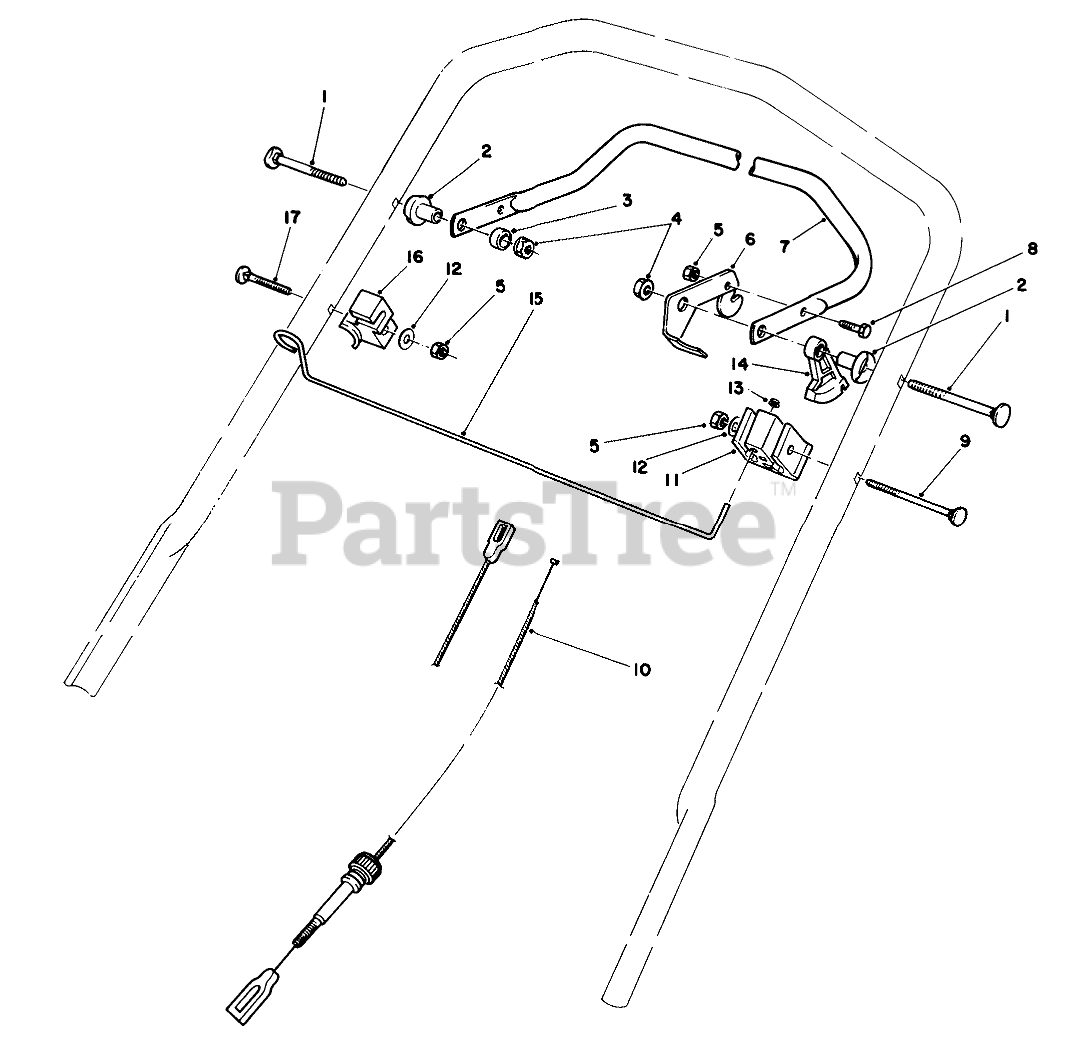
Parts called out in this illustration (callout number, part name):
1	5/16-18 X 2 HNDLE SCREW
2	SPACER-SUPPORT
3	SPACER-NYLON
4	NUT-LOCK, NI
5	NUT-LOCK, NI
6	Lever-Control
7	Bar-Control
8	SCREW-HH
9	HANDLE SCREW
10	CABLE-TRACTION
11	SUPPORT-CABLE
12	WASHER-FLAT
13	NUT-SPEED
14	LEVER-TRACTION
15	ROPE ROD PLATED
16	ROD CATCH
17	SCREW-HANDLE
